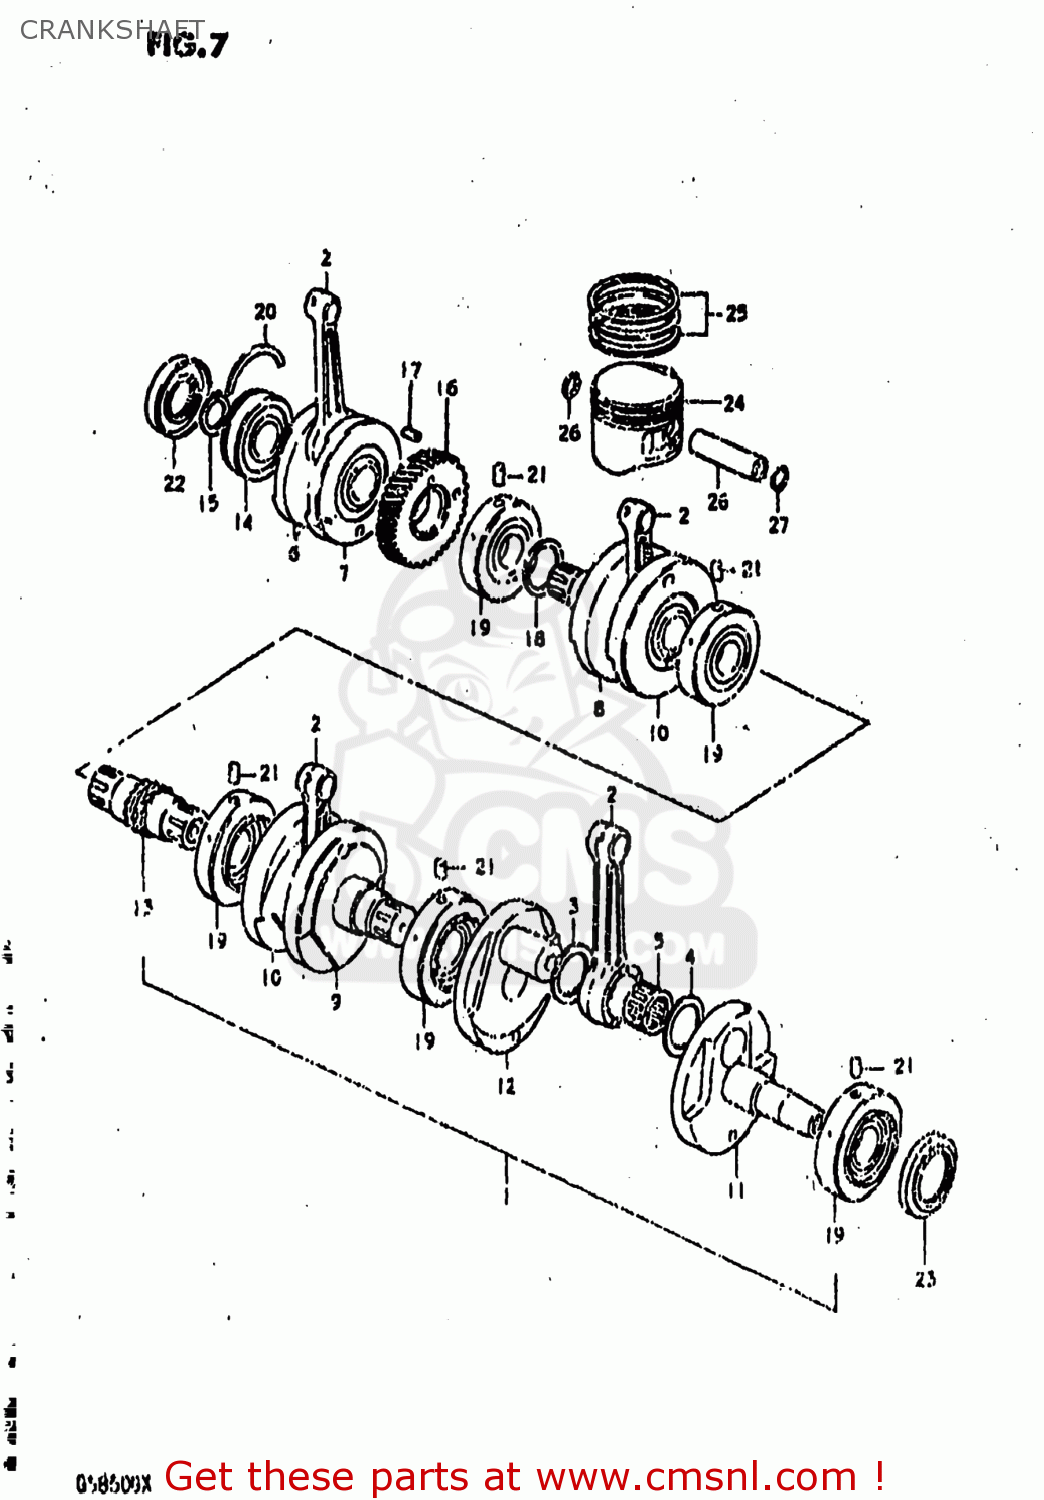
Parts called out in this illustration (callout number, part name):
1	CRANKSHAFT ASSEMBLY
2	CONNECTING ROD
3	WASHER (29X48X2)
4	WASHER (29X48X1)
5	BEARING(29X39X20)
6	CRANKSHAFT
7	WEB,CRANK,RIGHT
8	CRANKSHAFT
9	CRANKSHAFT, MIDDLE LH
10	WEB,CRANK,MIDDLE
11	CRANKSHAFT,LEFT
12	WEB,CRANK,LEFT
13	SHAFT,TIMING CHAIN DRIVE
14	BEARING(30X72X19)
15	CIRCLIP,30MM
16	GEAR,PRIMARY DRIVE
17	PIN
18	WASHER
19	BEARING
20	C RING
21	PIN
22	SEAL,OIL(30X72X11)
23	OIL SEAL
24	PISTON
25	RING SET,PISTON
26	PIN,PISTON
27	CIRCLIP
